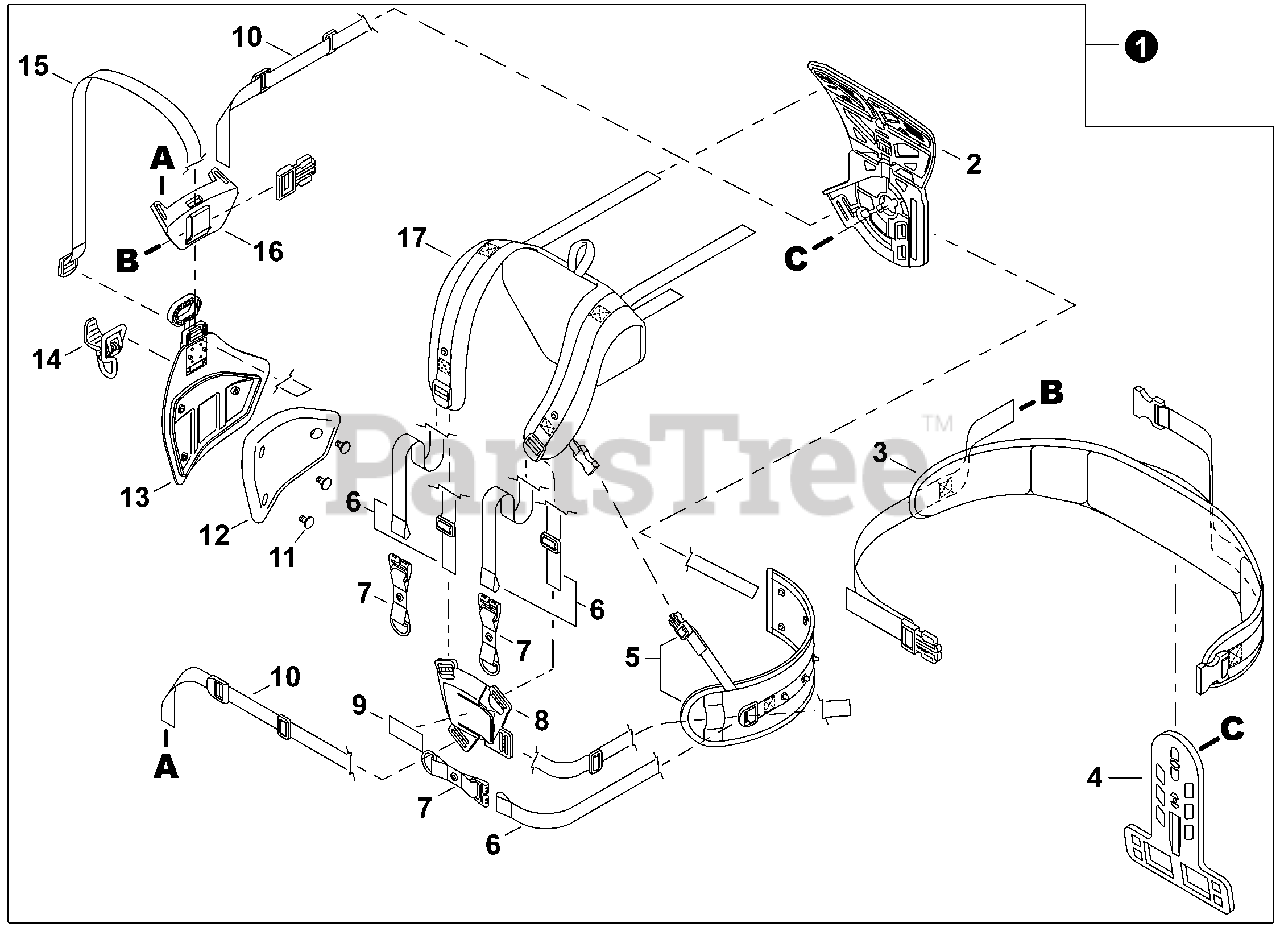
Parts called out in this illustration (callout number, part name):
1	HARNESS ASSY, BACKPACK
2	SUPPORT, HARNESS
3	BELT, HARNESS
4	SUPPORT, BELT
5	PAD, WAIST
6	STRAP, HARNESS
7	CONNECTOR, STRAP
8	BUCKLE SET, HARNESS
9	LABEL - ECHO
10	STRAP, HARNESS
12	CUSHION, HIP PAD
13	PAD, HIP
14	HOOK, HARNESS
15	STRAP, HARNESS
16	BUCKLE, HIP
17	PAD, SHOULDER
